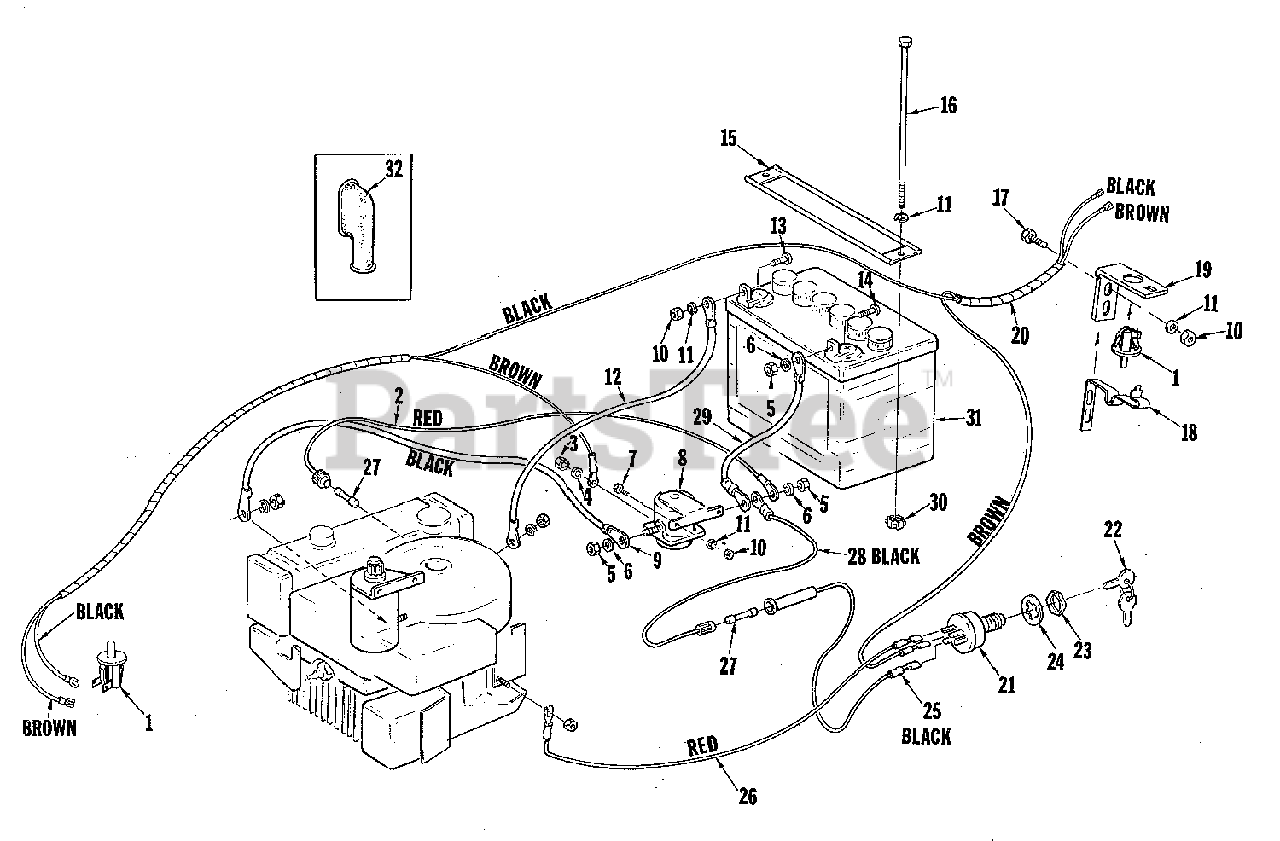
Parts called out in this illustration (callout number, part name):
1	SWITCH, Interlock w/Two Nuts
2	LEAD, Fuse Holder Engine to Solinoid
3	NUT, Hex, 10-32
4	LOCKWASHER, #10
5	NUT, Hex Fin, 5/16
6	LOCKWASHER, 5/16
7	CAPSCREW, 1/4-20 x 1/2
9	CABLE, Solinoid to Starter
10	NUT, Hex, 1/4-20
11	LOCKWASHER, 1/4
12	CABLE, Negative Battery Terminal to Engine Ground
13	BOLT, Round Head, 1/4-20 x 3/4
14	BOLT, Round Head, 5/16-18 x 3/4
15	HOLDOWN, Battery
16	CAPSCREW, Hex Head, 1/4-20 x 7
17	CAPSCREW, 1/4-20 x 3/4
18	CLIP, Spring
20	HARNESS ASSEMBLY, Interlock
24	LOCKWASHER, Intermediate Tooth
25	LEAD, Key Switch to Fuse Holder
26	LEAD, Magneto to Key Switch Ground
27	FUSE, 7-1/2 Amp
28	LEAD, Fuse Holder to Solinoid
29	CABLE, Solinoid to Positive Battery Terminal
30	RETAINER, Nut
31	BATTERY, 32 Amp Hour (T-8)
31	BATTERY, 24 Amp Hour (T-7)
32	COVER, Terminal
33	NUT, Flange Lock, 1/4-20
